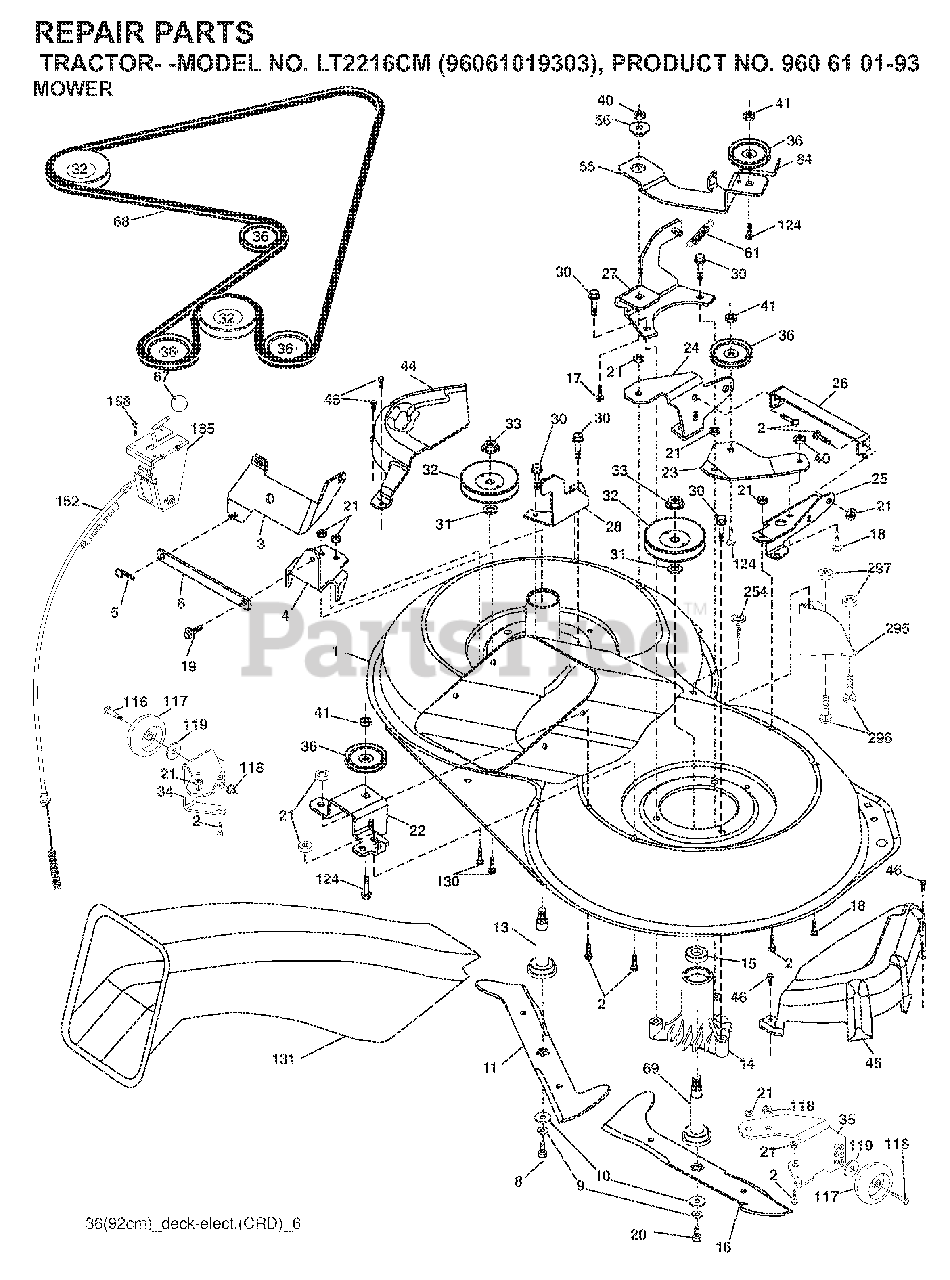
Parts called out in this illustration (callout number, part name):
2	BOLT
3	BRACKET
5	RETAINER-SPRNG RB
6	BAR SWAY
9	LOCKWASHER
10	WASHER.BLADE
13	SHAFT ASM VENT
14	HSG MANDREL
17	BOLT.3/8-14X1.25
19	BOLT SHD 5/16-18
21	LOCKNUT
24	BRACKET
25	BRACKET
28	BRACKET
30	SCREW, WASHER HEAD
31	WASHER.SPACER.MANDREL
32	PULLEY MANDREL
33	NUT.FLANGE.LOCK.TOP
36	PULLEY.IDLER.4.25
40	LOCKNUT
41	NUT LOCK FLG 3/8-16 UNC
45	MANDREL COVER
46	SCREW.1/4-20X5/8
56	SPACER.RETAINER.MOWER
67	KNOB T (3/8 HOLE)
69	SHAFT.ASM.W/LWR.BRG.RH.THREAD
84	KEEPER, BELT IDLER
116	BOLT.SHOULDER.3/8-16X3-5/8
117	WHEEL. GUAGE RALLY
118	NUT LOCK FLG 3/8-16 UNC
124	BOLT.3/8-16X1.50
131	CHUTE BAGGER
158	SCREW
185	HEAD ASM. CABLE CLUTCH
254	SCREW 3/8-16X1
296	BOLT
297	NUT CENTERLOCK
